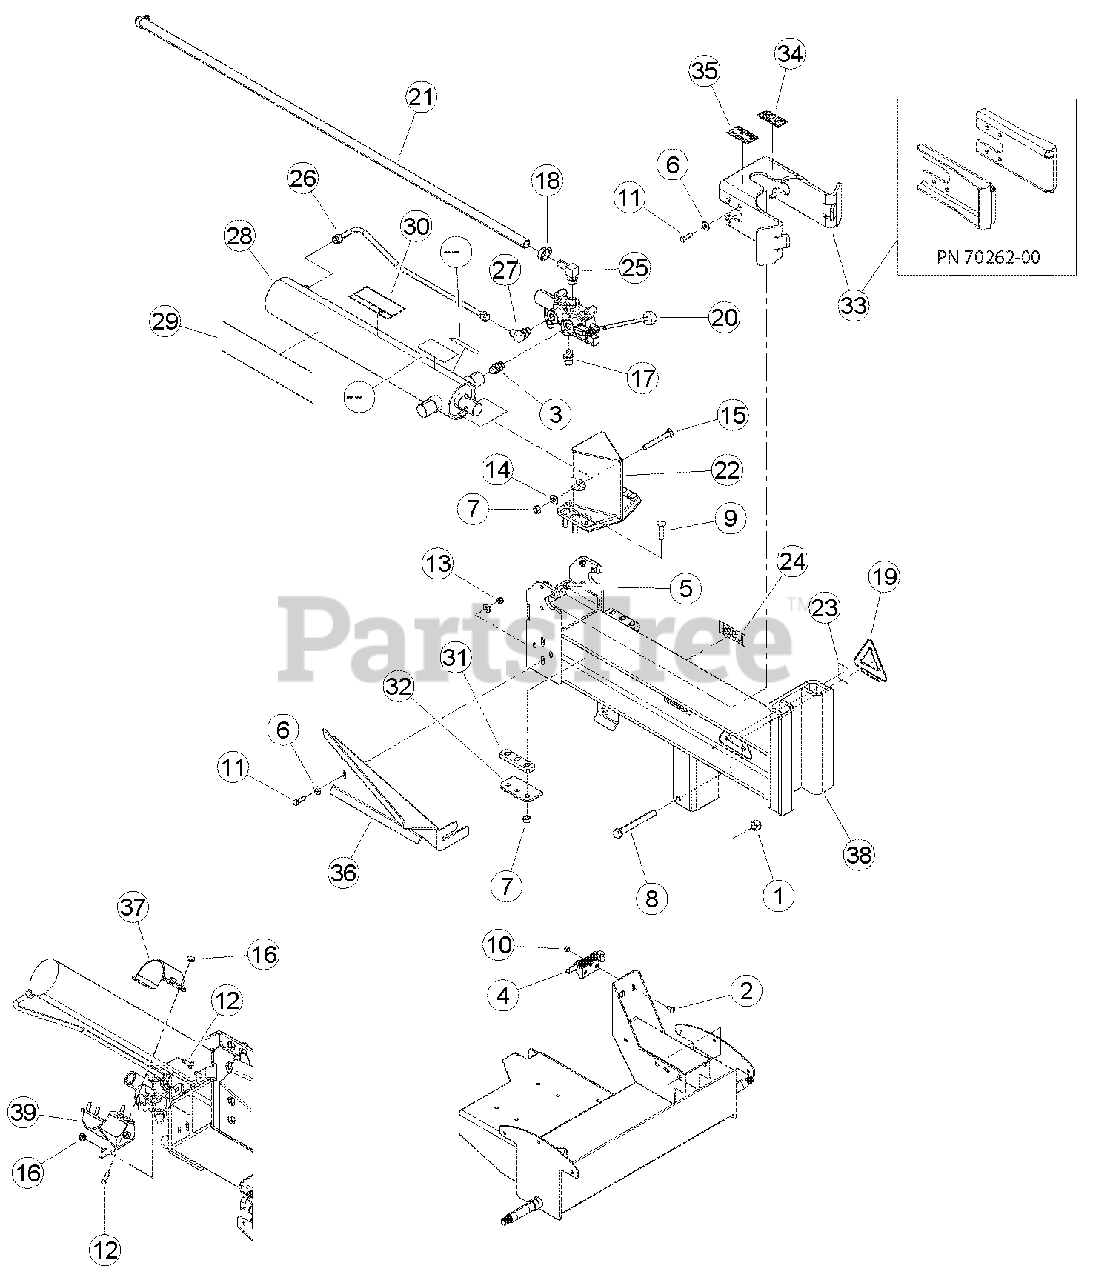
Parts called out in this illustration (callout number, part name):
1	NUT, 5/8-11 UNC NYLOCK
2	BOLT, 5/16-18 X 3/4 CRG GR5 SN
3	ADAPTER, -8 MORING / -8 MORING ADJ
4	LATCH, RH HINGE
5	NUT, 3/8" CENTERLOCK ZP
6	WASHER, 3/8" FLAT ZP (67PCS/LB)
7	NUT, 1/2 CENTERLOCK GRB ZP
8	BOLT, 5/8 X 5-1/2 HEX HD GR5 ZP
9	BOLT, 1/2 X 2 CRG GR5 ZP
10	NUT, 5/16 NE NYLOCK ZP
11	BOLT, 3/8 X 1-1/4" HEX HD GR5 ZP
12	BOLT, CARR 3/8*1-1/4"GR5 NC ZP
13	NUT, 3/8" NE NYLOCK ZP
14	WASHER, 1/2 HI-STRENGTH SAE ZP
15	BOLT, 1/2 X 4 CRG GR8
16	NUT, 3/8-16 NYLOCK FLANGE
18	CLAMP, 1-1/4" HOSE
19	DECAL, RECLAIM IT
20	VALVE, LOG SPLITTER
21	HOSE, 0.75 ID X 60" 100R4 HYD
22	WEDGE, CAST LOG SPLITTER
23	DECAL, ECHO BEARCAT QR CODE
24	DECAL, MODEL LS22
25	ADAPTER, -10 MORING/.75 90 DEG. HOSE
26	TUBE, HYDRAULIC LS21160
27	ADAPTER, -8 MORING / -8 MJIC 90 DEG.
28	CYLINDER, WELDED 4.00 X 24.00, SERVICE PART
29	DECAL, ECHO BEARCAT 14.12 X 4.00
30	DECAL, MUTILINGUAL MANUAL
31	SPACER, BOTTOM WEDGE
32	PLATE, CAST WEDGE BOTTOM
34	DECAL, CRUSHING ISO
35	DECAL, CYLINDER OPERATION (ISO)
36	CHUTE, ENGINE GUARD
37	CLAMP, CYLINDER SUPPORT TOP
38	22 TON BEAM W/ DECALS
39	WELDMENT, CYLINDER SUPPORT LS22
